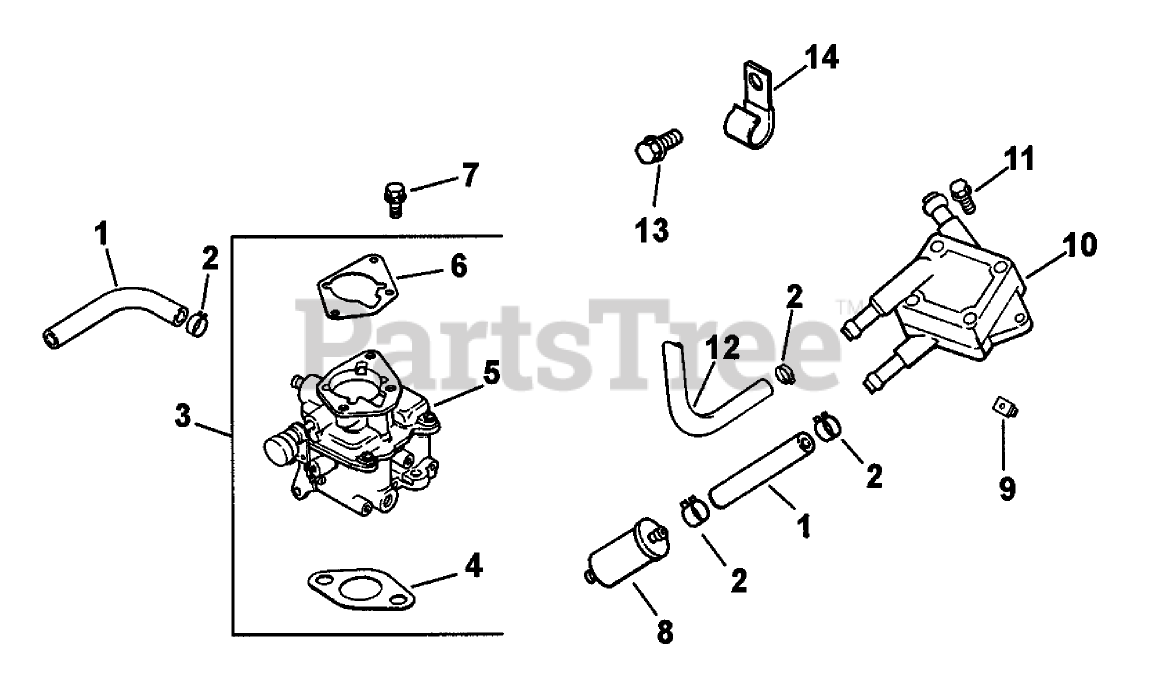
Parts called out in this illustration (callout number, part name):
1	Line-Fuel (9.5)
2	CLAMP-HOSE, SPRING (1/2)
3	Kit-Carburetor (w/gasket)(Includes 4-6)
4	GASKET-BASE, AIR CLEANER
5	Carburetor ASM
6	Gasket-Carburetor
7	SCREW-FLANGE (M6X1.0X30)
8	Filter-Fuel
9	Nut-Plastic
10	PUMP-FUEL
11	SCREW-TAP (M6X1.7X18)
12	Line-Fuel, Flexible (15.5)
13	Screw-HF (M6x1.0x12)
14	CLIP-CABLE
